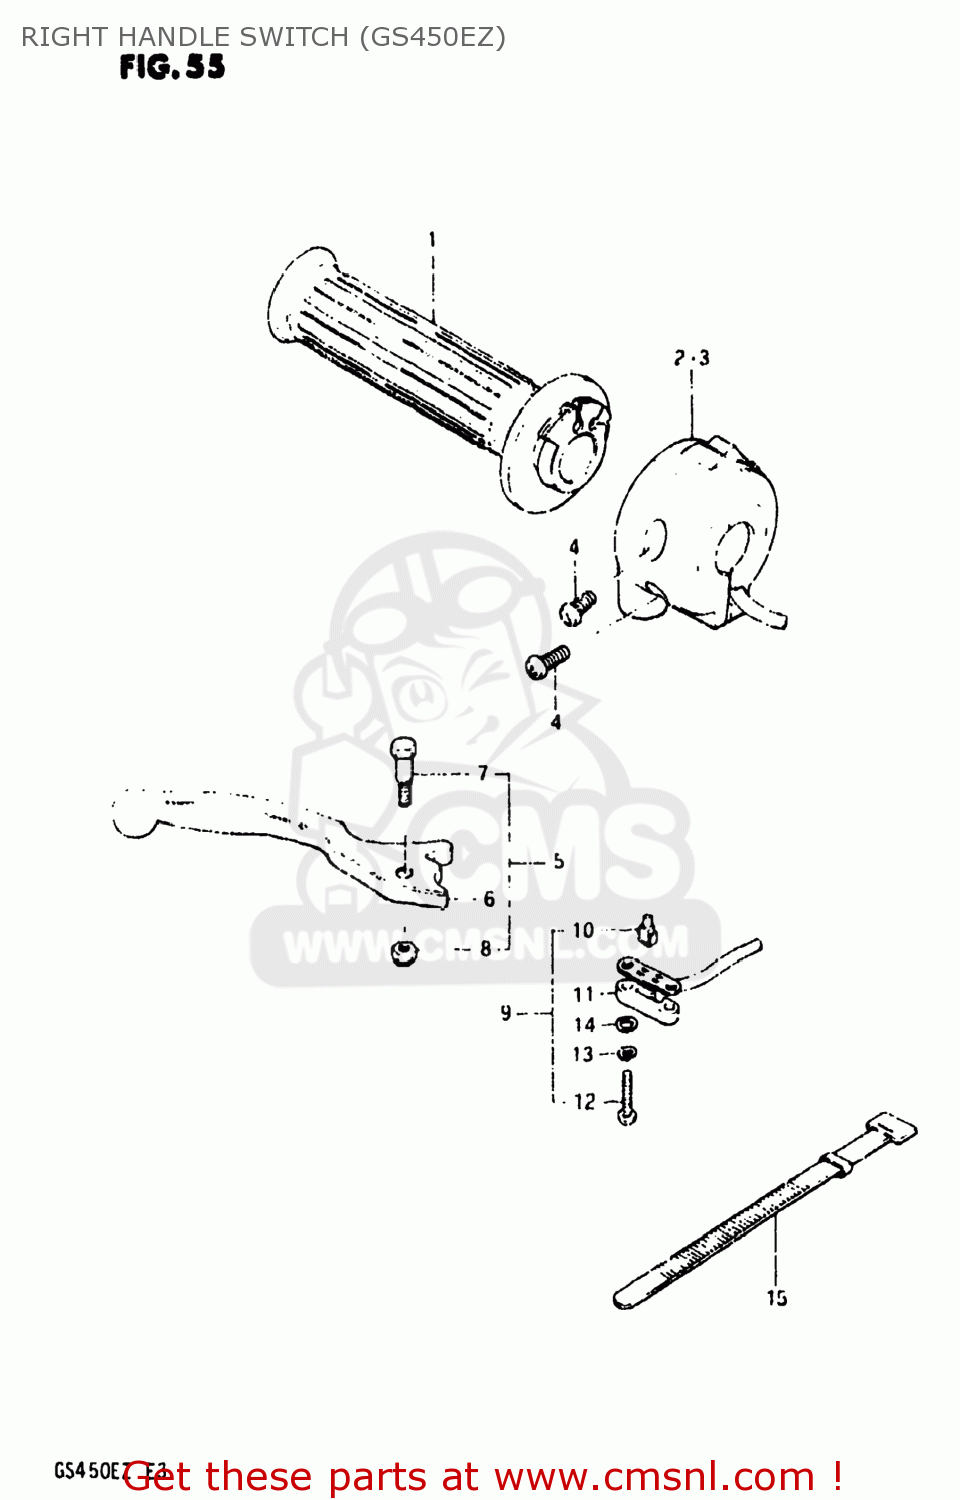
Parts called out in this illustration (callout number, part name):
1	GRIP,THROTTLE
2	SWITCH ASSEMBLY,HANDLE,RIGHT
3	SWITCH ASSEMBLY,HANDLE,RIGHT
4	SCREW
5	LEVER,BRAKE
6	LEVER,BRAKE
7	BOLT
8	NUT 6MM
9	SWITCH ASSEMBLY
10	CONTACT,SWITCH
11	COVER,FR BK TERMINAL BASE
12	SCREW
13	LOCK WASHER
14	WASHER
15	CLAMP(L:120)
